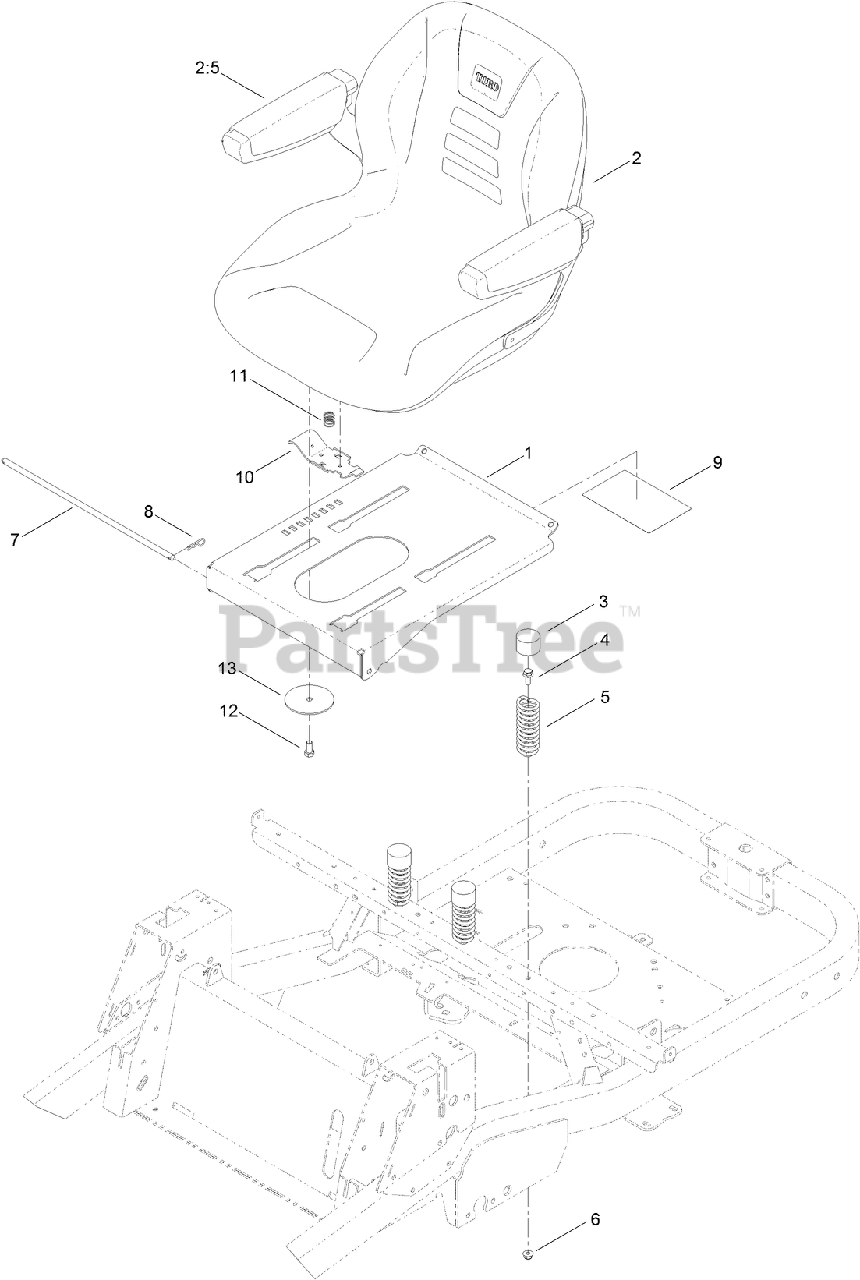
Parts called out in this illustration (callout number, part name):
1	PAN-SEAT
2	18 INCH SEAT ASM
2:5	ARMREST KIT
3	CAP-PROTECTOR
4	SCREW-HHF
5	SPRING-COMPRESSION
6	NUT-HF, NI
7	ROD-STOP
8	PIN-COTTER
9	DECAL-MAINTENANCE
10	LATCH-SEAT
11	SPRING-COMPRESSION
12	SCREW-HH
13	WASHER-SEAT
